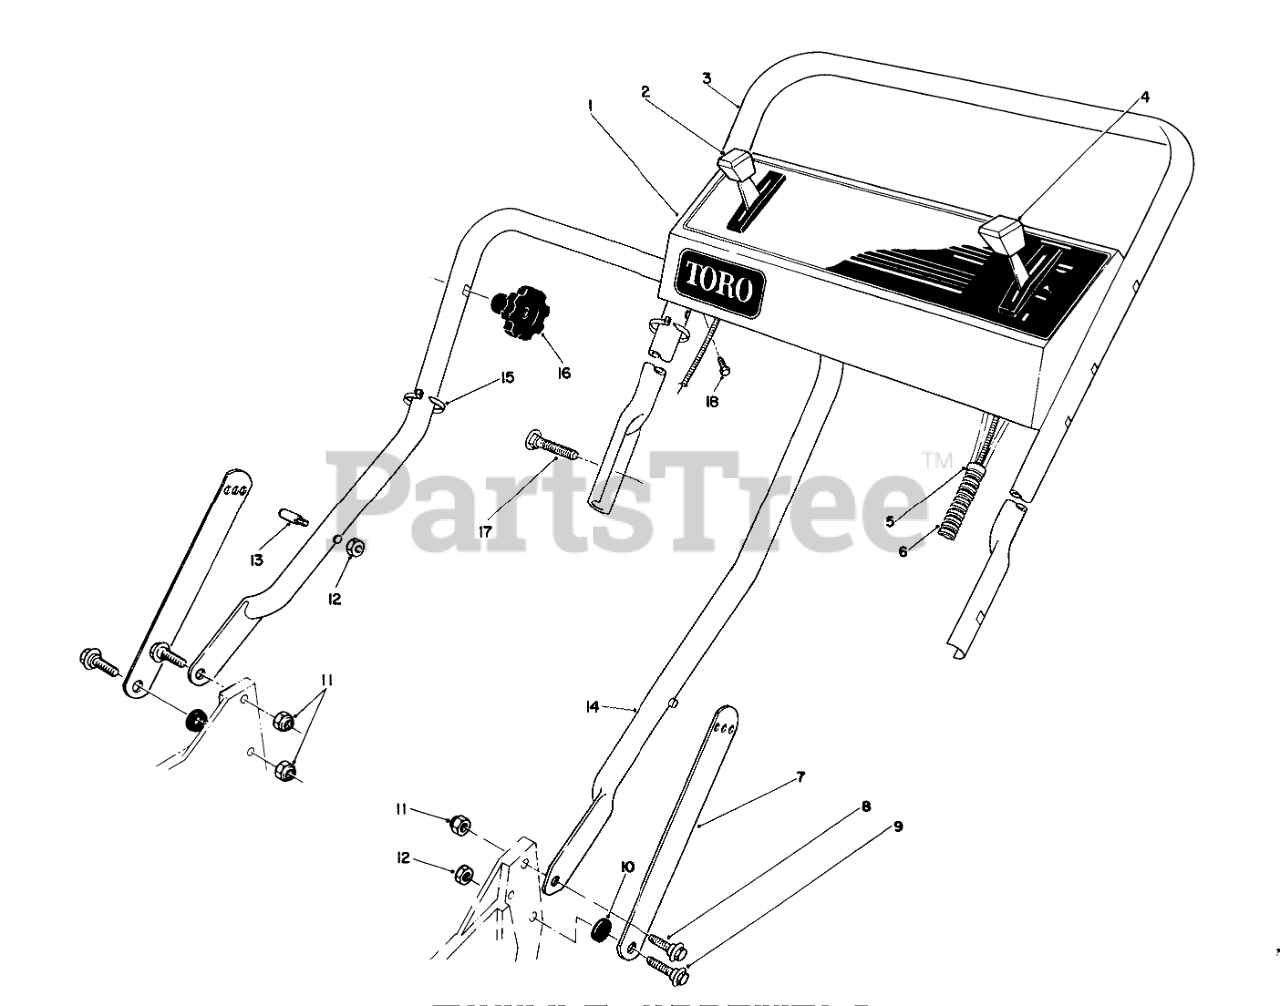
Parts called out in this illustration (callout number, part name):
1	SILK SCRN CONTROL PANEL
2	GROUND SPEED CONTROL
3	UPPER HANDLE
4	THROTTLE CONTROL
5	FITTING-RING
6	CONTROL CABLE COVER
7	Handle Latch
8	SCREW-SHOULDER
9	SCREW-SHOULDER
10	SPACER
11	NUT-LOCK, NI
12	NUT-LOCK, NI
13	HANDLE PIN
14	LOWER HANDLE ASM
15	TIE-CABLE
17	5/16-18 X 2 HNDLE SCREW
18	SCREW-HWHTF
